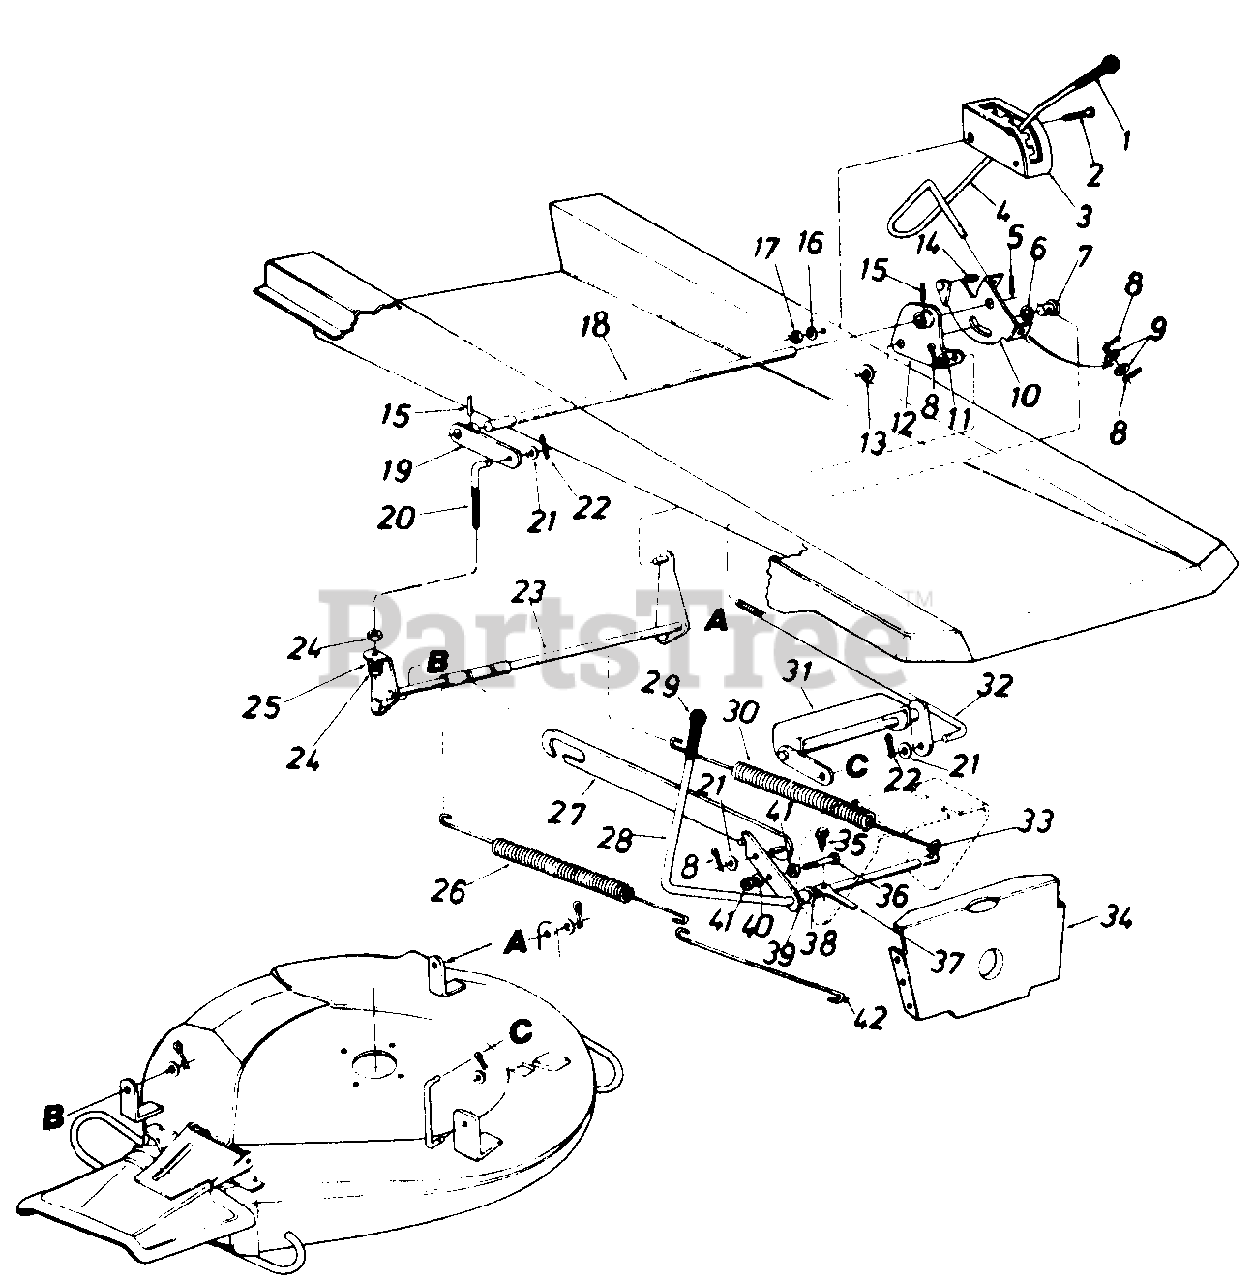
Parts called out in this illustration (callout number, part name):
2	Truss Mach. Scr. 5/16-18 x .75" Lg.
5	Spring Pin Spir. 3116" Dia. x 1.50" Lg.
6	Fl-Wash. .385" I.D. x .87" O.D.
7	Adj. Ferrule Deck Lift Handle
8	Cotter Pin 118" Dia. x 1.00" Lg.
9	Fl-Wash. .531" I.D. x .930" O.D.
10	Deck Lift Handle Retainer Ass'y.
11	Fl-Wash. .385" I.D. x .87" O.D.
12	Deck Lift Brkt. Ass'y.-L.H.
13	Fl-Wash. .635" I.D. x 1.04" O.D.
14	Compression Spring .50" Dia. x 1.0" Lg.
15	Spring Pin Spir. 114" Dia. x 1.50" Lg.
16	L-Wash. 5/16" I.D.
17	Hex Nut 5/16-18 Thd.
18	Rear Hgt. Adj. Shaft
19	Deck Lift Brkt. Ass'y.-R.H.
20	Deck Adj. Scr. 3/8-16 Thd.
21	Fl-Wash. .385" I.D. x .87" O.D.
22	Intern. Cotter Pin 1/2" Dia.
23	Deck Link Ass'y.-Rear
24	Hex Nut 3/8-16 Thd.
25	L-Wash. 3/8" I.D.
26	Extension Spring .73" O.D. x 13.84" Lg.
27	Deck Drive Control Bracket
28	Blade Engagement Lever Ass'y.
30	Extension Spring .73" O.D. x 1 3.89" Lg.
31	Deck Lift Ass'y.-Front
32	Deck Lift Connecting Rod
33	Clevis Pin Special .250" Dia.
34	Pivot Bar Bracket
35	Hex TT-Tap Scr. 1/4-20 x .75" Lg.
36	Hex Bolt 5/16-18 x 1.50" Lg. (Grade 5)
37	Switch Actuator
38	Fl-Wash. .531' I.D. x .930" O.D.
39	Spacer .511" I.D. x .70" O.D. x.38" Lg.
40	L-Wash. 5/16" I.D.*
41	Hex Nut 5/16-18 Thd.
42	Spring Hook
